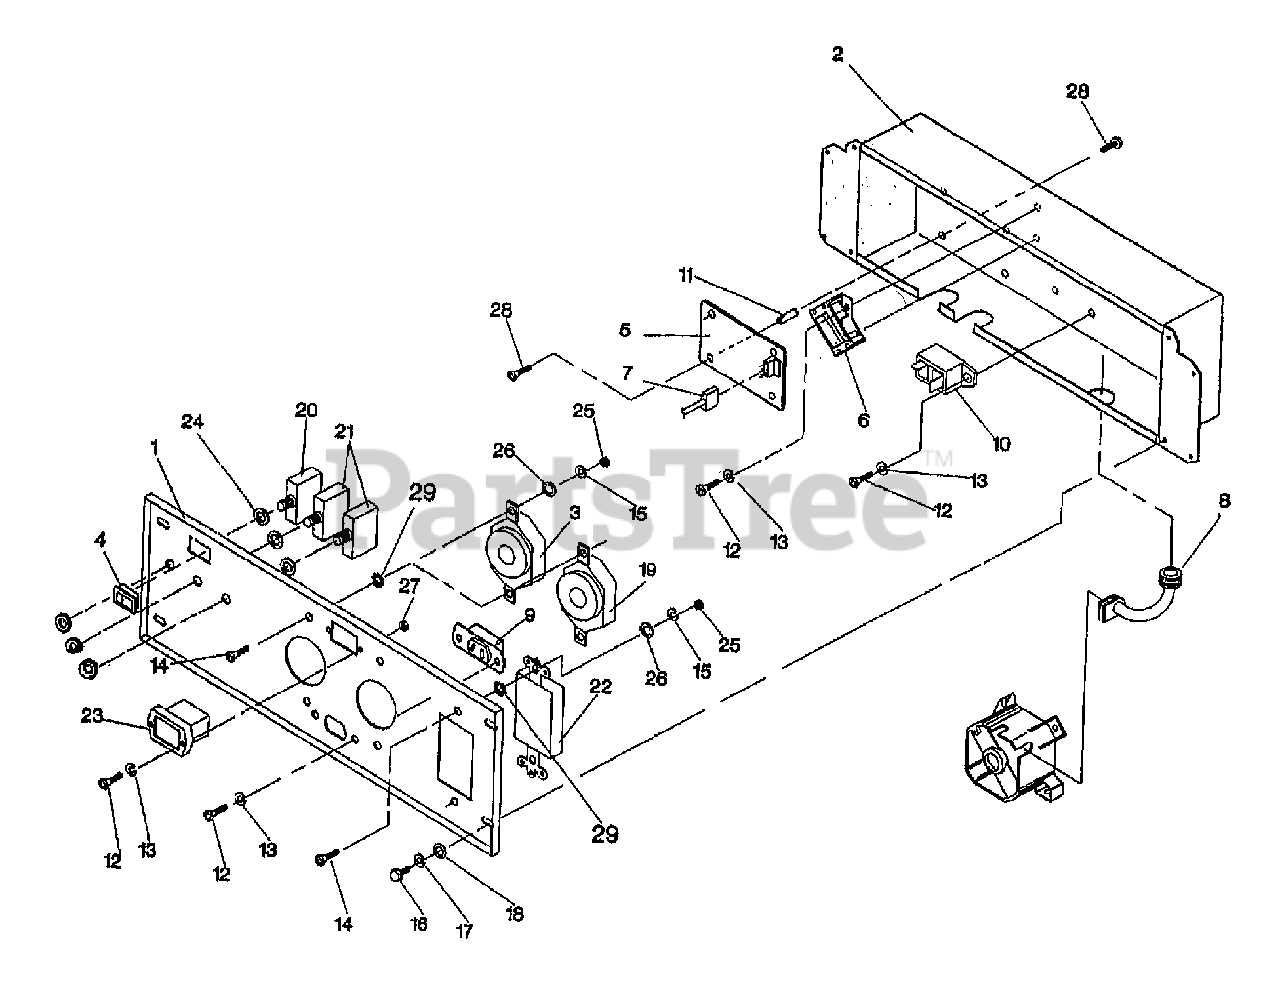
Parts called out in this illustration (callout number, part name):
1	PANEL-CONTROL (4000W GEN)
2	ASSM-FLYWHL 28 DEG TIMING(GEN)
3	OUTLET-120V 20A (4000W GEN)
4	SWITCH-IDLE CONTROL (GENERATOR
5	BOARD-SYSTEM CONTROL (GENERATO
6	TRANSFORMER-IDLE CONTROL (GEN)
7	ASSM-WIRE HARNESS (GENERATOR)
8	CONNECTOR-RUBBER GROMMET (GEN)
9	BRKT&OUTLET-12V DC (GEN)
10	CIRCUIT BREAKER-12V 10A (GEN)
11	STAND-OFF HEX 3/4" LONG (GEN)
12	SCR-PH M3-.5X10MM
13	WASHER-LOCK M3 (GEN)
14	SCR-PH M4-.7X10MM
15	WASHER-LOCK M4 (GEN)
16	SCR-PH M5-.8X12MM
17	WASHER-LOCK M5 (GEN)
18	WASHER-LOCK M5 (GEN)
19	OUTLET-120V 30A
20	CIRCUIT BREAKER-30A (GEN)
21	CIRCUIT BREAKER-20A (GEN)
22	OUTLET-DUPLEX GFCI 120V 20A (G
23	METER-HOUR (GENERATOR)
24	WASHER-LOCK INTERNAL
25	NUT-HEX M4-0.7 (GEN)
26	WASHER-FLAT M4
27	NUT-HEX M3-0.5 (GENERATOR)
28	SCR-SELF TAP #6-32 X 3/8 (GEN)
29	WASHER-LK #8 (GENERATOR)
